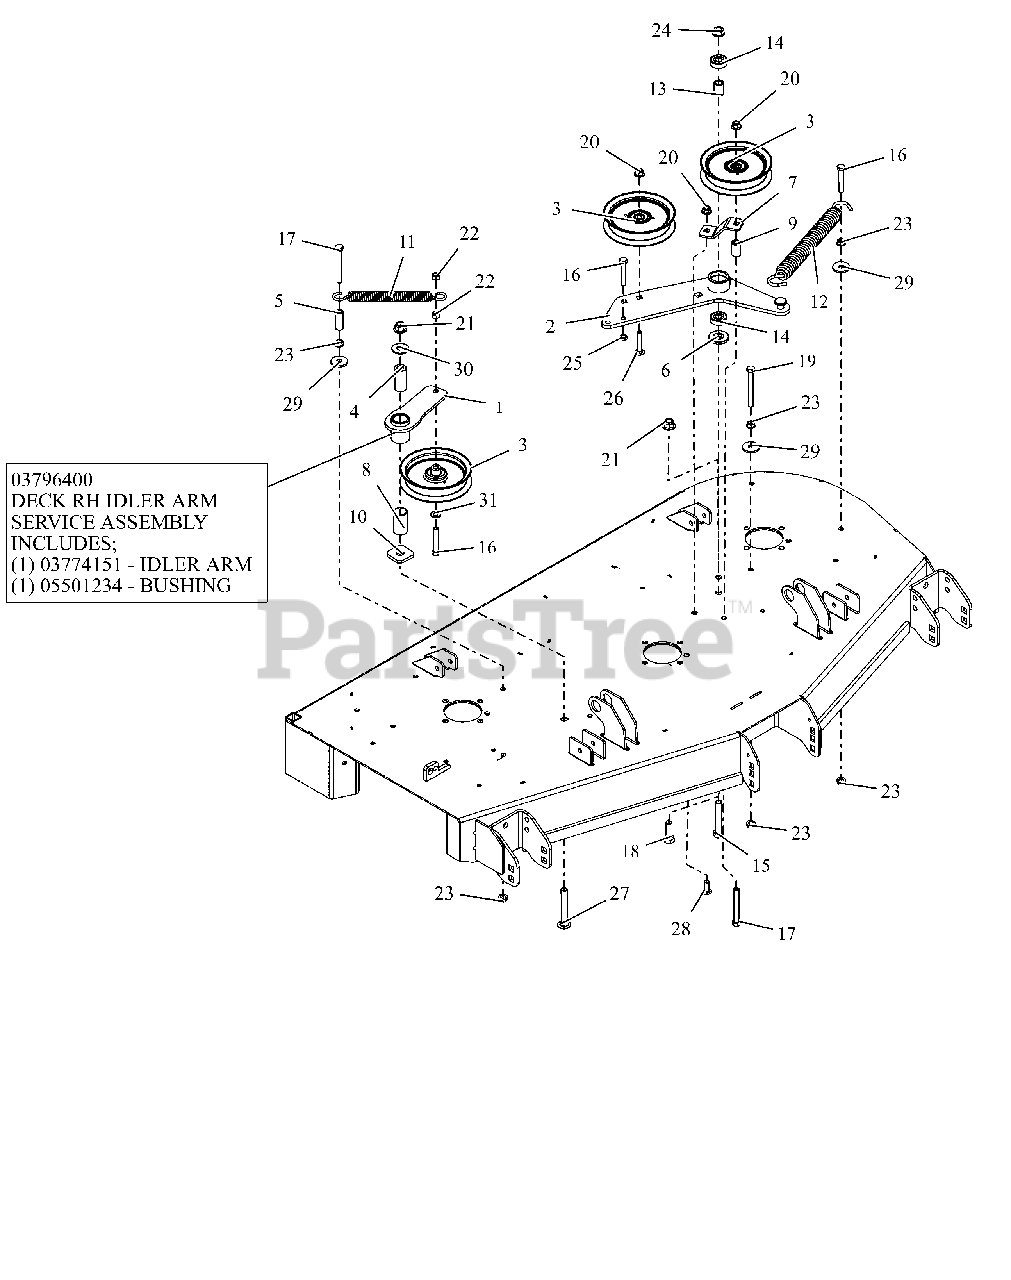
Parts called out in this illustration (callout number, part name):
1	WMT, IDLER ARM - BLACK
1	ASM, IDLER ARM (DECK)
2	DECK PTO IDLER ARM WLDMT - BLK
3	IDLER, FLAT 5.00"
4	BSHG, SPCR .502X.997X2.03 PM
5	SPACER, .375IDX.625ODX1.66 PM
6	SPACER, IDLER ARM
7	PTO FIXED IDLER MTG BRKT -RED
8	BSHG, 1.00X1.125X1.937
9	BUSHING, SLV .380X.750X1.190
10	WSHR-FLT .640X1.75X.250
11	SPRING, EXTENSION
12	SPRING, EXTENSION
13	SPACER .510 X .75 X 1.1485
14	BRG-BALL .500X1.38X.437
15	BLT, HEX .50-13X3.00 G5 ZCC
16	BLT,HEX .38-16X2.25 G5 ZCC
17	BLT, HEX .38-16X3.25 G5 ZCC
18	BLT,HEX .50-13X1.50 G5 ZCC
19	BLT, HEX .38-16X3.50 G5 ZCC
20	NUT,NYL-FLG .38-16 GF ZCC
21	NUT,NYL-FLG .50-13 GF ZCC
22	NUT-LK-CTR .38-16 ZC120
23	NUT, SPNLK-FLG .38-16 G5 ZCC
24	NUT-LK-CTR-FLG .500-13 GG ZCC
25	NUT-JAM .375-16 G2 ZCC
26	BLT,RHSSN.375-16X2.00 G5 ZCC
27	BLT, RHSN .50-13X3.50 G5 ZCC
28	BLT,RHSSN .38-16X1.00 G5 ZCC
29	WSHR,FLT .406X1.375X.135 ZCC
30	WSHR,FLT .563X1.375X.109 ZCC
31	WSHR,FLT .406X.812X.065 ZCC
